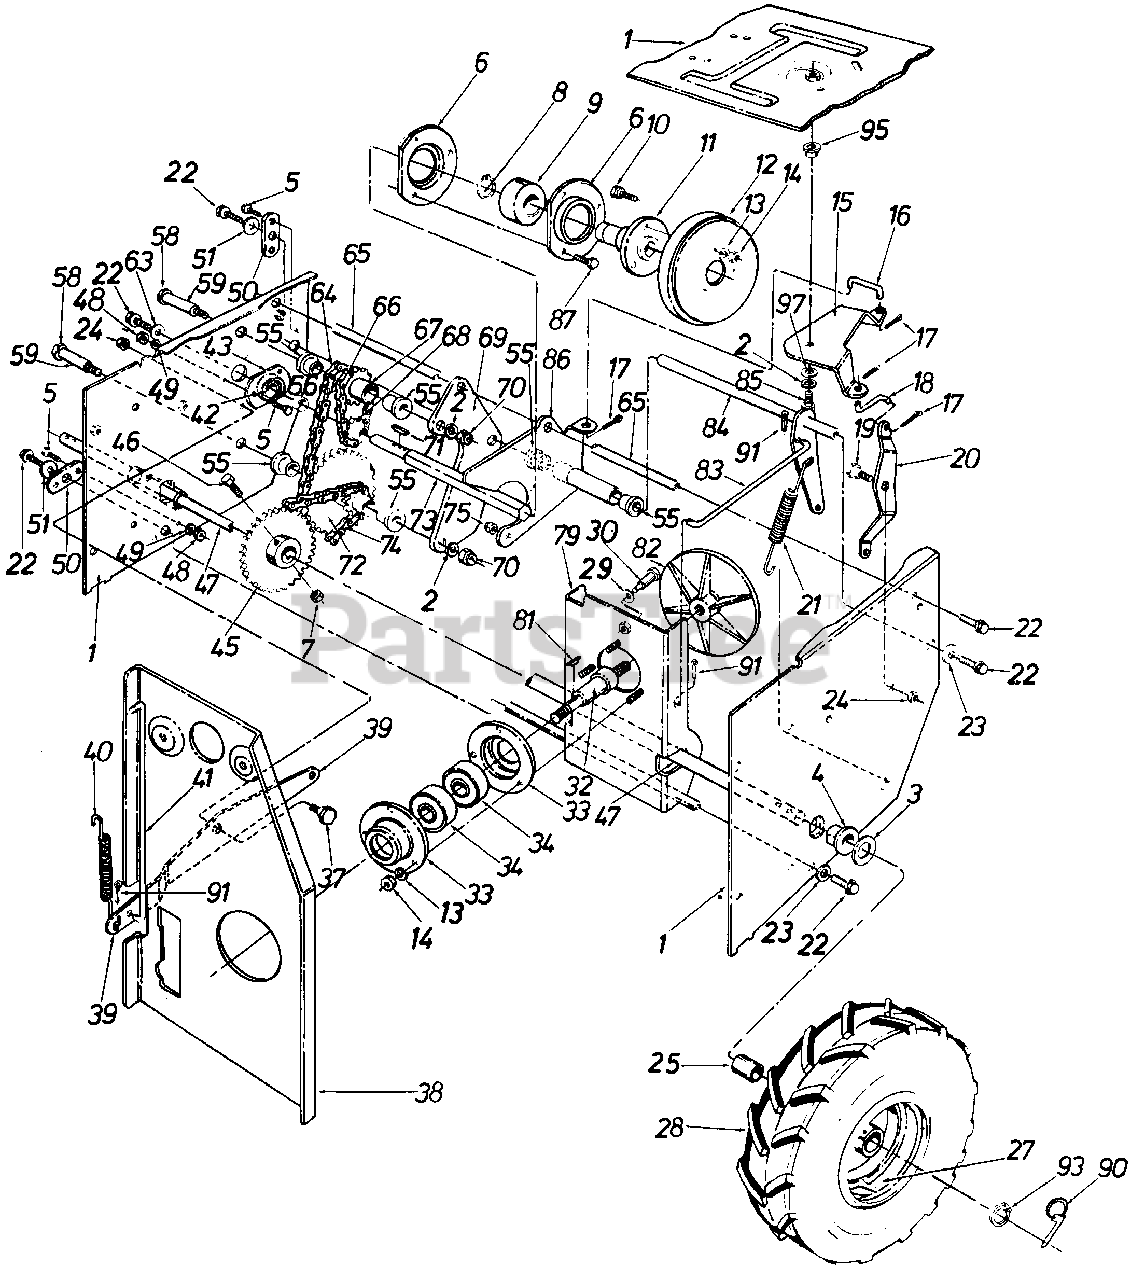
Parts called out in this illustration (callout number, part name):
1	Frame Ass'y.
2	L-Wash. 3/8 Scr.*
3	Fl-Wash. 1.03" I.D. x 1.62" O.D. x .03
4	Flange Brg. 1.0" I.D.
5	Hex Bolt 1/4-20 x .62" Lg.*
6	Bearing Housing
7	Hex L-Nut 5/16-24 Thd.
8	Snap Ring for 1.00" Dia. Shaft
9	Ball Brg. 25 mm x 52 mm x 15 mm
10	Hex Sems Scr. 5/16-18 x .75" Lg.*
11	Friction Wheel Adapter
12	Friction Wheel Ass'y.
13	L-Wash. 5/16" Scr.*
14	Hex Nut 5/16-18" Thd.*
15	Sliding Linkage Brk't.
16	Sliding Rod .31" Dia. x 2.00" Lg.
17	Cot. Pin 3/32" Dia. x .75" Lg.*
18	Shifting Linkage Rod .31" Dia. x 2.25" Lg.
19	Shld. Scr. .625" Dia. x .170" Lg.
20	Shifting Linkage Brk't.
21	Extension Spring .73 O.D. x 4.31" Lg.
22	Hex L-Scr. 5/16-18 x .62" Lg.*
23	Fl-Wash. .345 I.D. x .75 O.D. x .060
24	Hex Cent. L-Nut 3/8-16 Thd.
25	Bearing
27	Wheel Rim Ass'y.
28	Wheel Ass'y. Comp. 16 x 4.5 L.H.
29	Bel l-Wash.
30	Shld. Scr.
32	Drive Plate Spindle
33	Bearing Housing
34	Ball Brg. .787 I.D. x 1.85 O.D. x .56
37	Shld. Scr. .625" Dia. x .170" Lg.
38	Engine Brk't. Ass'y.
39	Auger Clutch Brk't.
40	Extension Spring .38 O.D. x 3.18" Lg.
41	Auger Clutch Rod .31" Dia. x 10.62" Lg.
42	Ball Bearing
43	Bearing Housing
45	28 Tooth Sprocket Hub Ass'y.
46	Hex Scr. 5/16-24 x 1.75" Lg.
47	Axle Free Wheeling
48	Hex Nut 1/4-20 Thd.
49	L-Wash. 1/4" Scr.
50	Pivot Axle Brk't.
51	Fl-Wash. .345" I.D. x .75" O.D. x .060
55	Flange Brg. .630" I.D.
56	Spacer.51" I.D. x .69" O.D. x .44
58	Hex Scr. 3/8-24 x 2.75" Lg.
59	Sprocket Hub Tubing 1.900" Lg.
63	Bell-Wash. .345" I.D. x .88 O.D. x .060
64	#41 Chain 1/2" Pitch x 43 Links
65	Sliding Support Axle
66	#41 Chain 1/2" Pitch x 19 Links
67	9 and 14 Teeth Sprocket Hub Ass'y.
68	8 Teeth Sprocket
71	#9 Hi-Pro Key 3/32 x 5/8" Dia.
72	9 and 32 Teeth Sprocket Hub Ass'y.
73	Hex Shaft
74	#420 Chain 1/2" Pitch x 37 Links
75	Hex Ins. Jam L-Nut 1/4-28"
82	Aluminum Drive Plate
83	Drive Clutch Rod .31" Dia. x 7.38" Lg.
84	Drive Clutch Brk't. Ass'y.
85	Hex Scr. 3/8-16 x 1.00" Lg.
86	Sliding Brk't. Ass'y.
87	Hex Scr. 1/4-28 x .62" Lg.
90	Klick Pin
91	Internal Cot. Pin 5/16 Dia.
93	Snap Ring 1.0" Shaft
95	Shld. Spacer 5/8" I.D.
97	Fl-Wash.
